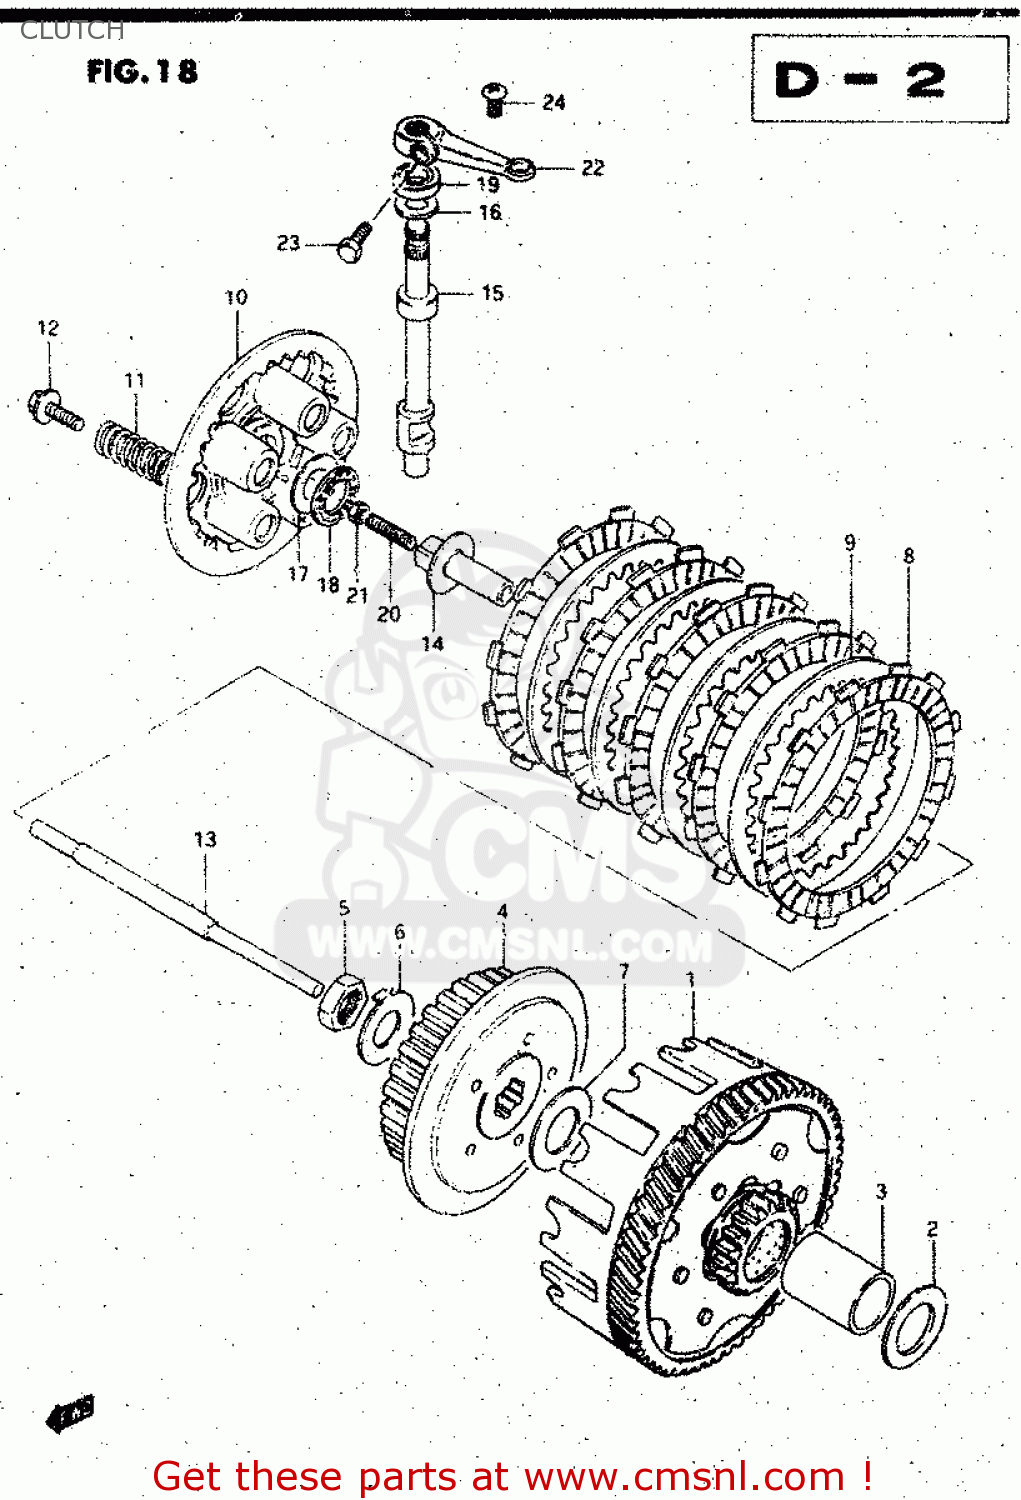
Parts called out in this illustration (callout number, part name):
1	GEAR ASSY,PRI DRIVEN(NT:59)
2	WASHER
3	SPACER
4	HUB,CLUTCH SLEEVE
5	NUT
6	WASHER
7	WASHER
8	PLATE,CLUTCH DRIVE(T:3.0) (NAS)
9	PLATE,CLUTCH DRIVEN (NAS)
10	PLATE,CLUTCH PRESSURE
11	SPRING
12	BOLT 5X16
13	ROD,CLUTCH PUSH
14	PEACE
15	CAMSHAFT,CLUTCH RELEASE
16	WASHER,THRUST
17	WASHER(15.5X28X1)
18	BEARING(15X28X2)
19	SEAL,OIL(10X20X6)
20	SCREW(6X25)
21	NUT
22	ARM,CLUTCH RELEASE
23	BOLT
24	SCREW 6X10
